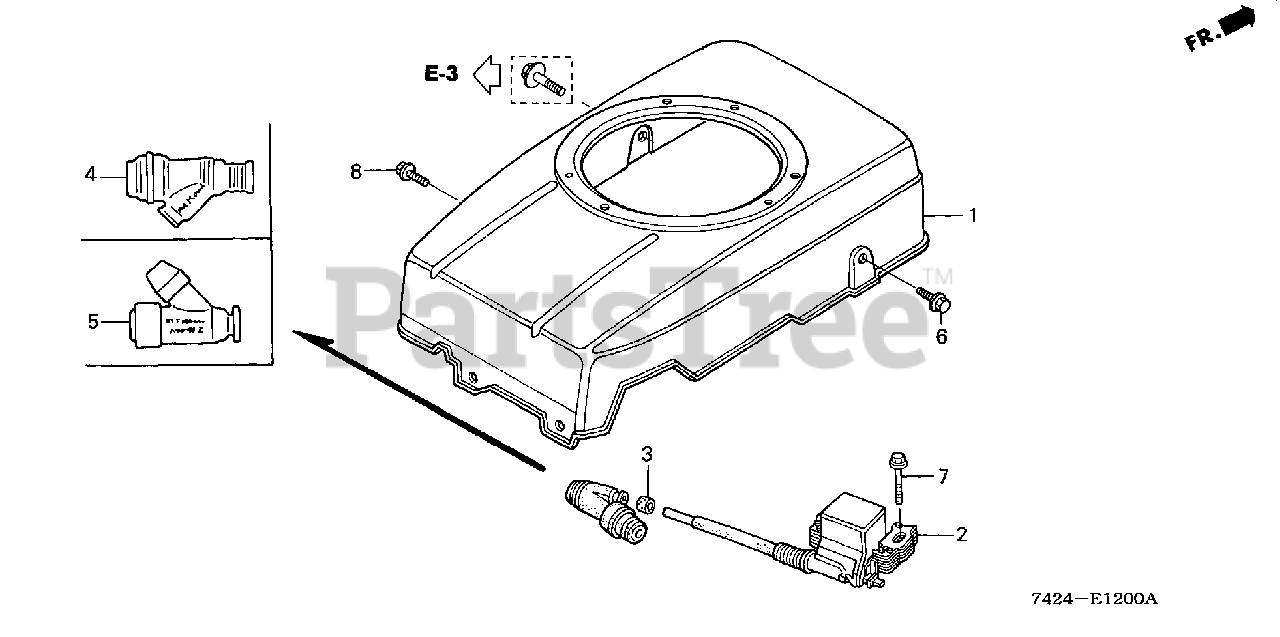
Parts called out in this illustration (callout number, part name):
1	COVER, FAN *R8* (BRIGHT RED)
1	COVER, FAN *R280* (POWER RED)
2	COIL ASSY., IGNITION
3	GROMMET, IGNITION WIRE
4	CAP ASSY., NOISE SUPPRESSOR
5	CAP ASSY., NOISE SUPPRESSOR
6	BOLT, FLANGE (6X12) (CT200)
7	BOLT, FLANGE (6X25)
8	BOLT, FLANGE (6X10)
